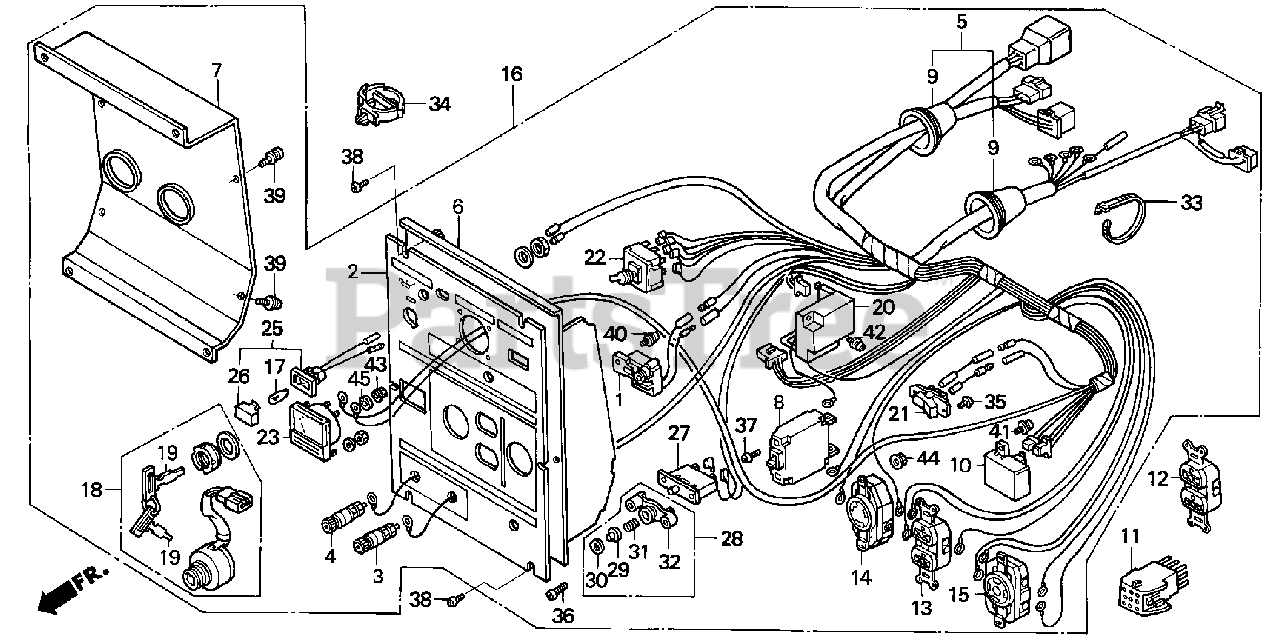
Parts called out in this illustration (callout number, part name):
1	ALERT UNIT, OIL
2	MARK, CONTROL INDICATION
3	TERMINAL, D.C. OUT (+)
4	TERMINAL, D.C. OUT (-)
5	HARNESS ASSY., CONTROL (EXS-A)
6	PANEL, CONTROL (EXS-A)
7	COVER, CONTROL
8	BREAKER, CIRCUIT (18A)
9	GROMMET, MAIN WIRE
10	DIODE ASSY.
11	CONNECTOR ASSY.
13	RECEPTACLE (20A-125V)
14	RECEPTACLE (3-PRONG) (30A/125V)
15	RECEPTACLE (30A/125-250V)
16	PANEL ASSY., CONTROL
16	PANEL ASSY., CONTROL (EXS-A)
17	BULB, WEDGE BASE (12V/2W)
18	SWITCH ASSY., COMBINATION
19	KEY
20	THROTTLE UNIT ASSY., AUTO
21	SWITCH ASSY., AUTO THROTTLE
22	SWITCH ASSY., VOLT CHANGE
23	METER ASSY., VOLT (300V)
25	SOCKET ASSY., LAMP (GREEN)
26	LENS (GREEN)
27	PROTECTOR, CIRCUIT (DC)
28	LENS ASSY., PROTECTOR
29	LENS
30	CAP, LENS
31	SPRING, COIL
32	HOLDER, LENS
33	TIE, CABLE
34	STRAP, WIRE HARNESS (25MM) (BLACK)
35	SCREW, PAN (3X6)
36	SCREW, PAN (3X12)
37	SCREW, PAN (4X6)
38	SCREW, PAN (5X10)
39	SCREW-WASHER (4X8)
40	SCREW-WASHER (4X10)
41	SCREW-WASHER (4X12)
42	SCREW-WASHER (5X12)
43	NUT, FLANGE (3MM)
44	NUT, FLANGE (4MM)
